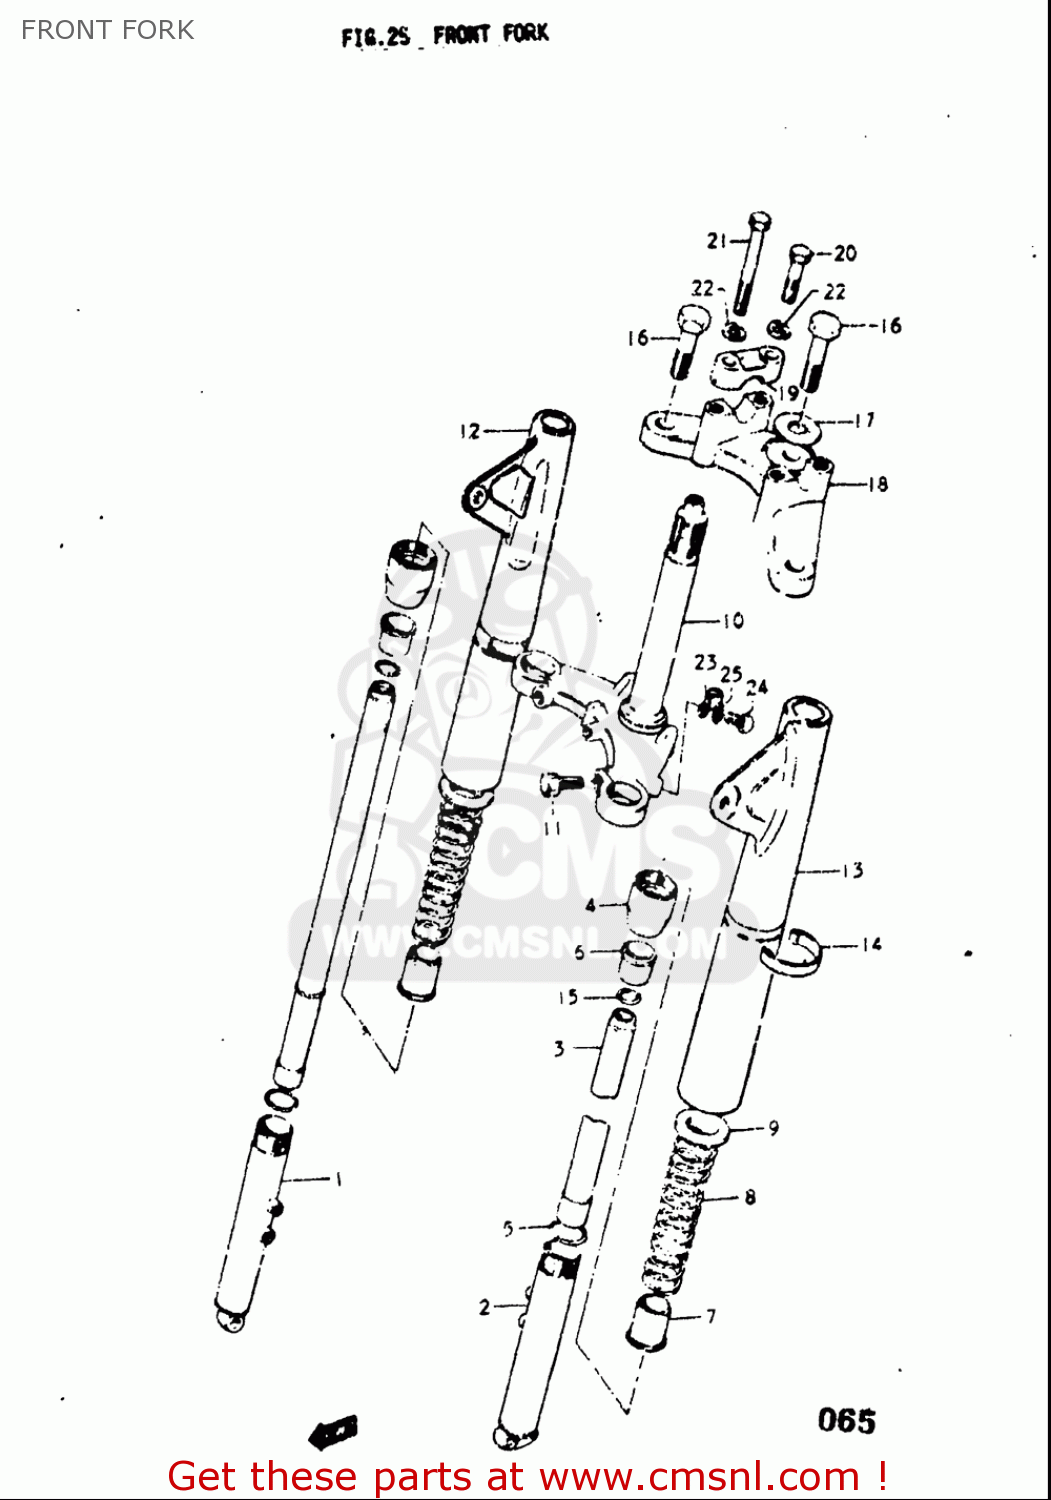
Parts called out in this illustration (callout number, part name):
3	TUBE,FORK,INNER
4	NUT,FORK OUTER TUBE
6	GUIDE,FORK INNER TUBE
7	GUIDE,FRONT FORK SPRING
8	SPRING
11	BOLT
12	BRACKET SET,HEADLAMP
13	BRACKET SET,HEADLAMP
15	O RING
17	WASHER,STEM HEAD(10.5X30X3.2)
19	HOLDER,HANDLEBAR
20	BOLT
22	WASHER,LOCK
23	CLIP,BRAKE CABLE
24	SCREW
25	WASHER,LOCK
